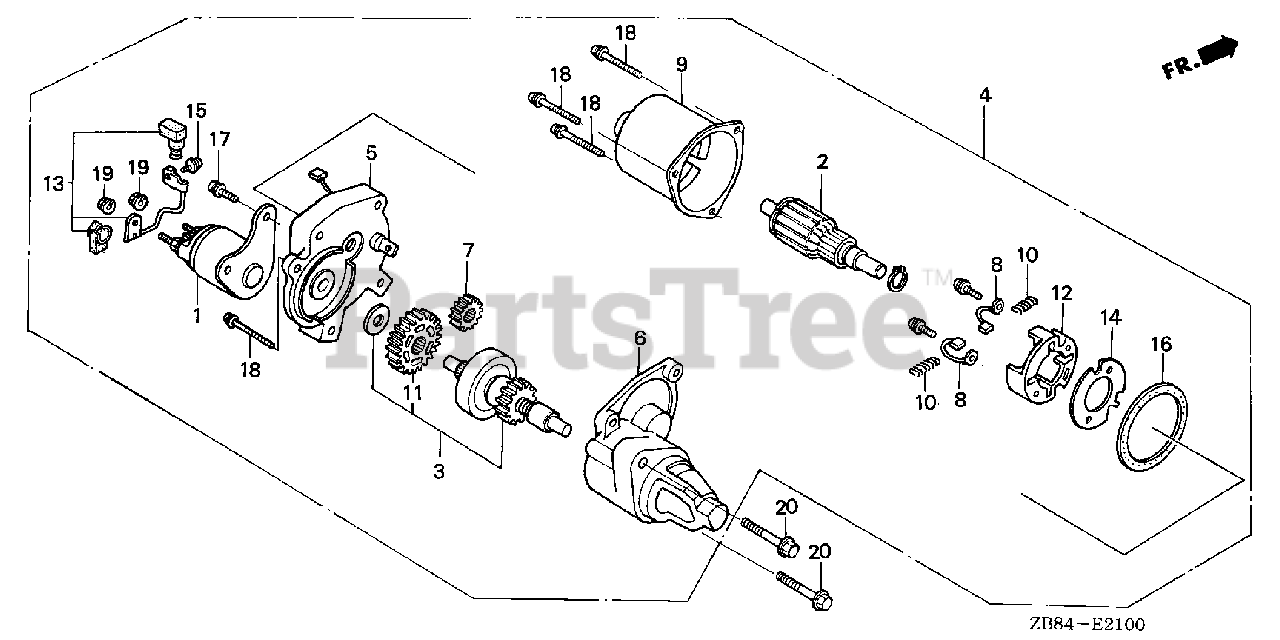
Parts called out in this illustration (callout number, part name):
1	CONTACTOR ASSY.
3	CLUTCH, OVERRUNNING
4	MOTOR UNIT, STARTER
5	BRACKET, CENTER
6	BRACKET, FR.
7	GEAR, DRIVE PINION
10	SPRING, BRUSH RETURN
11	GEAR, REDUCTION
12	HOLDER, BRUSH
13	WIRE, WATER COVER
15	SCREW-WASHER (4X6)
17	SCREW-WASHER (5X14)
17	BOLT-WASHER (5X14)
18	SCREW-WASHER (5X3)
19	NUT-WASHER (6MM)
20	BOLT, FLANGE (8X35)
